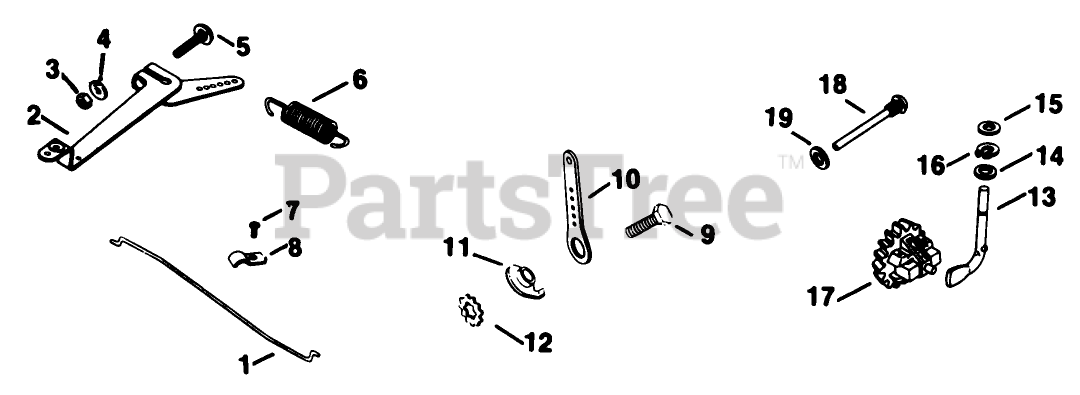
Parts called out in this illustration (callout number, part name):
1	Link-Govenor
2	Arm-Governor
4	Washer
5	Screw-Round Hd.
6	Spring-Governor
7	Screw
9	Screw-HH
10	Lever-Speed Control
11	Stop-Govenor
12	Washer-Lock
13	Shaft-Govenor
14	Washer
15	Washer
16	Retainer-Governor
17	Governor Gear
18	Pin-GovemorStop
19	Washer
